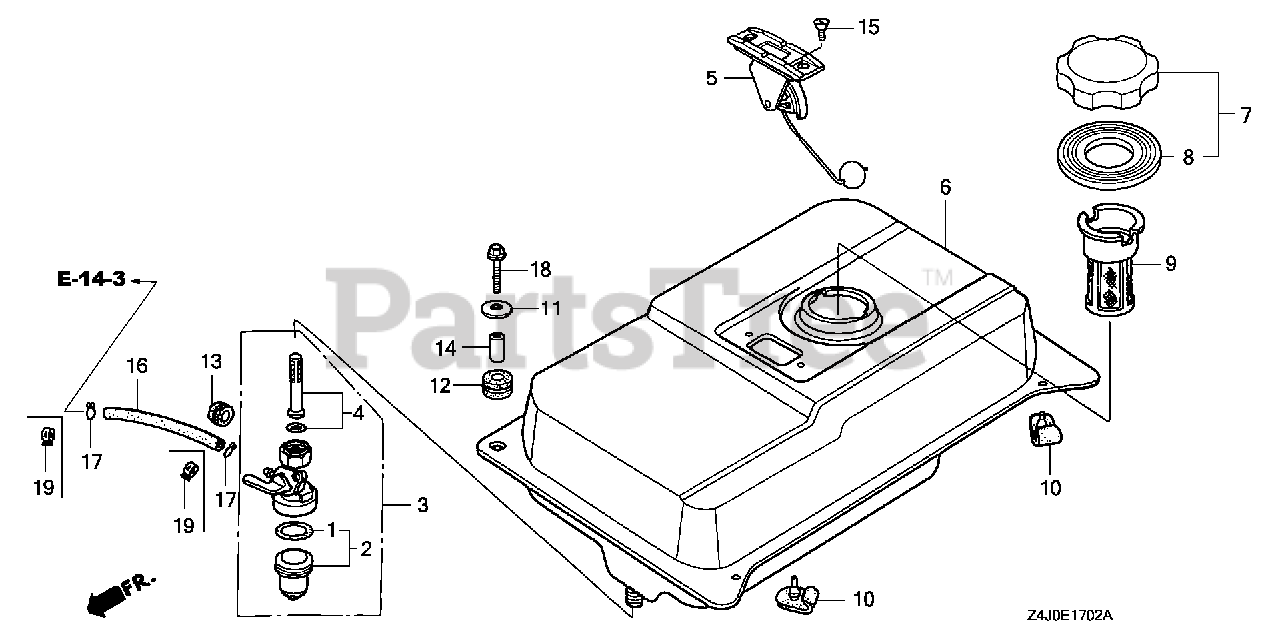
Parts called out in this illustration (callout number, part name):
1	GASKET SET, PETCOCK (CONTAINS 1 LARGE & 1 SMALL. USE AS NEEDED)
2	CUP, FUEL STRAINER
3	PETCOCK ASSY.
4	SCREEN SET
16	TUBE, FUEL (4.5X180) (FKM)
16	BULK HOSE, FUEL (4.5X3000) (4.5X180)
17	CLIP, TUBE (B8)
19	CLAMP, TUBE (D8)
